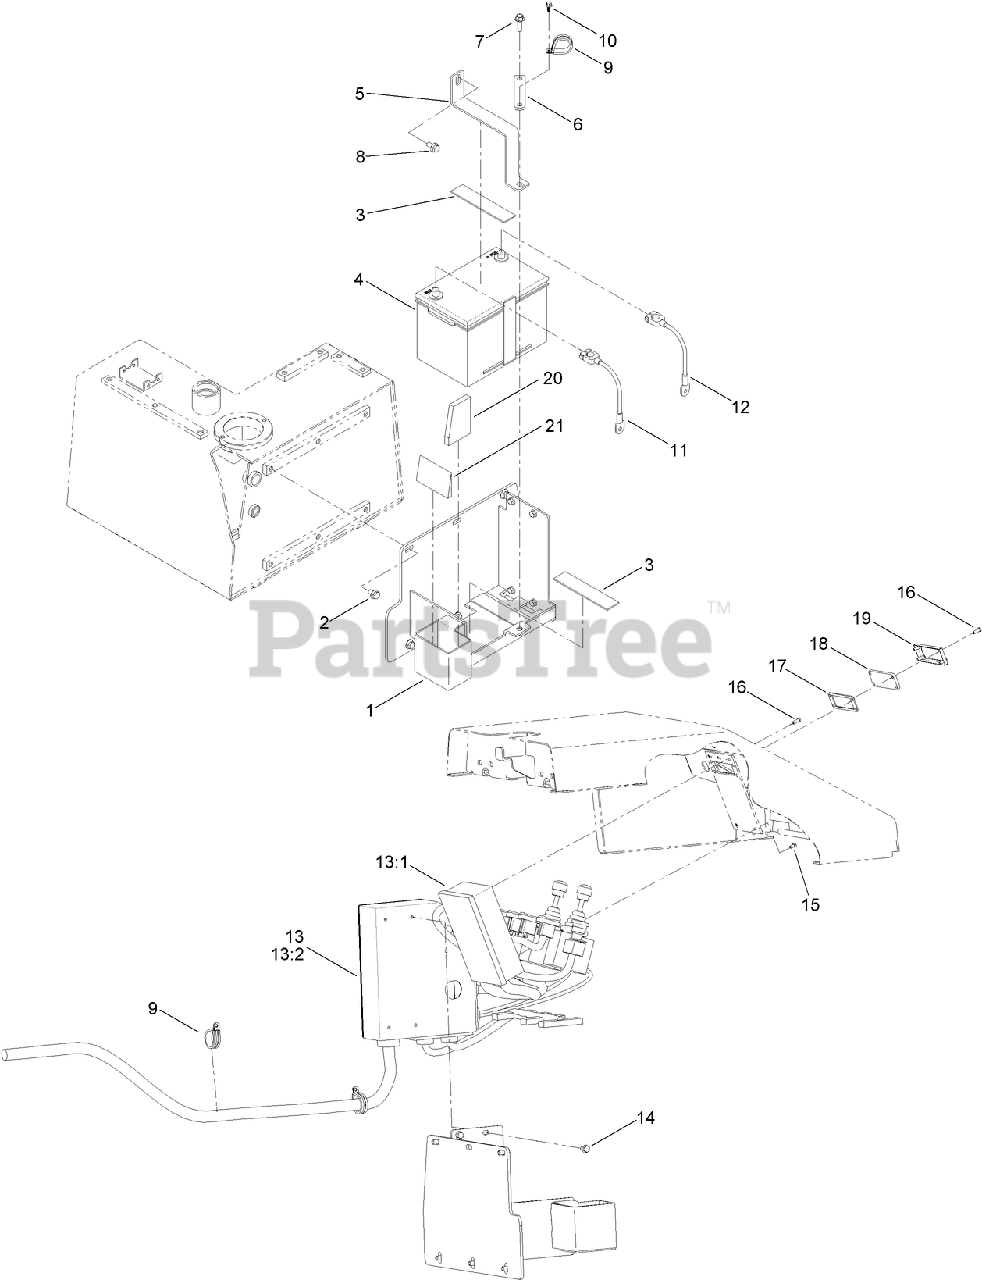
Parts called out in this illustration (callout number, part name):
1	PANEL-ELECTRICAL
2	SCREW-HHF
3	RUBBER
4	BATTERY-775CCA, 12V AGM
5	STRAP-BATTERY
6	BRACKET-WIRE HARNESS
7	SCREW-HHF
8	SCREW-HHF
9	CLAMP
10	SCREW-HHF
11	CABLE-BATTERY, BLACK
12	CABLE-BATTERY, RED
13	CONTROL SYSTEM KIT
13:1	BOX-CONTROL IGNITION, ELECTRONIC
13:2	JUNCTION BOX ASM
14	SCREW-HHF
15	SCREW-HH
16	SCREW-HSBH
17	GASKET-COVER
18	COVER
19	COVER-LENS
20	PAD-FOAM
21	PAD-FOAM
